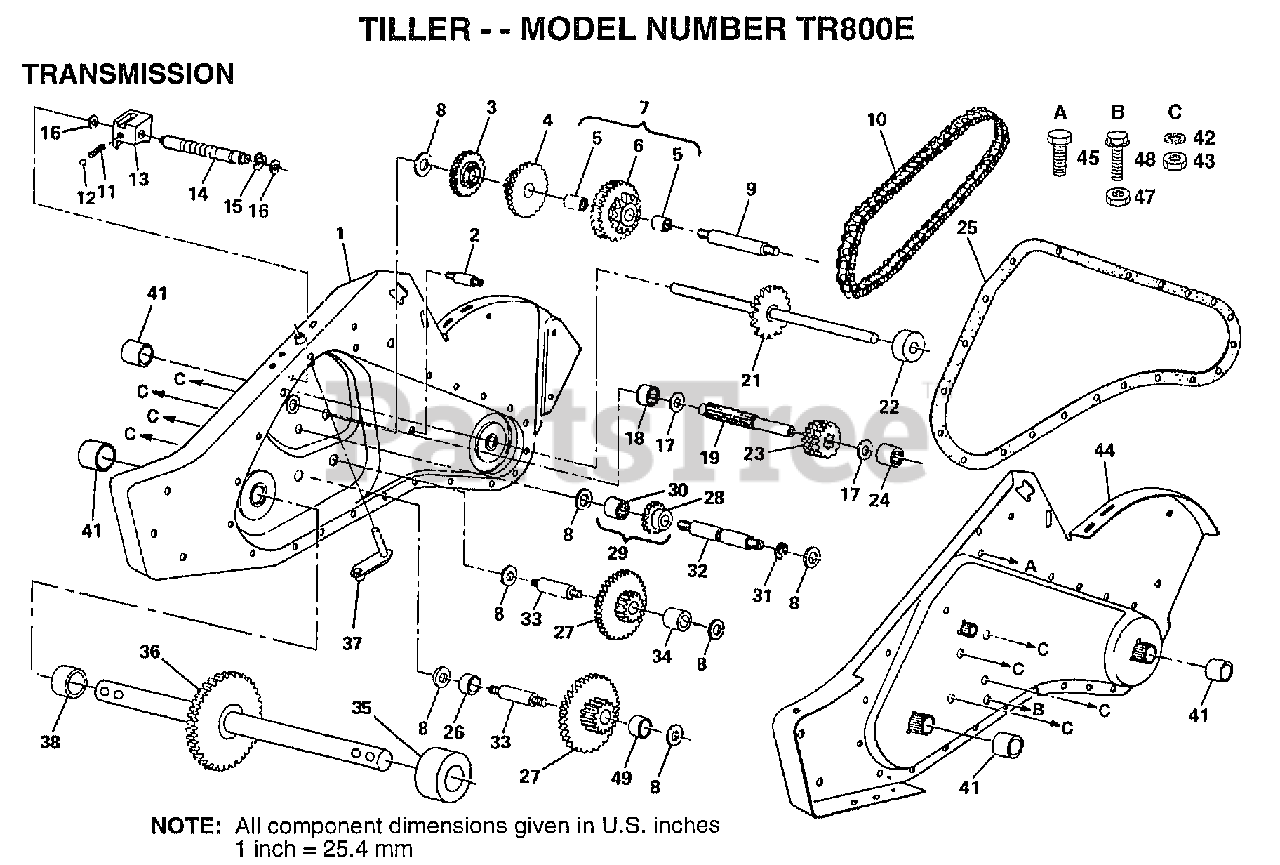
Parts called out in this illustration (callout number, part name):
2	BOLT TI
3	REVERSE GEAR TI
4	CLUSTER GEAR TI
5	"CRT, BEARING"
7	SPROCKET ASSY TI
8	WASHER
9	REDUCTION SHFT TI
10	CHAIN TI
11	SPRING-SHIFT CRT
13	SHIFT FORK TI
14	SHIFT SHAFT TI
15	KLIP RING
16	WASHER SEAL
17	"T, BEARING"
18	"TI, BEARING"
19	SHAFT INPUT
21	SHAFT TINE CRT
22	SPACER CRT
23	INPUT PINION TI
24	NEEDLE BRNG LT
25	GEARCASE GSKT TI
26	SPACER CRT
27	GEAR CLUSTER CRT
28	REVERSE GEAR TI
29	GEAR ASSY TI
30	NEEDLE BEARING TI
31	KLIP RING
32	REVERSE SHAFT TI
33	SHAFT CRT
34	SPACER CRT
35	SPACER CRT
36	SHAFT ASSY CRT
37	BRACKET ASM SHIFT
38	SPACER CRT
41	SEAL ASM-OIL
42	LOCKWASHER
43	NUT.ASF.HEX.7/16
44	"GEARCASE ASSY,LH"
45	SCREW 5/16-18X5/8
47	NUT.HEX.5/16-18
48	BOLT TI
49	SPACER CRT
